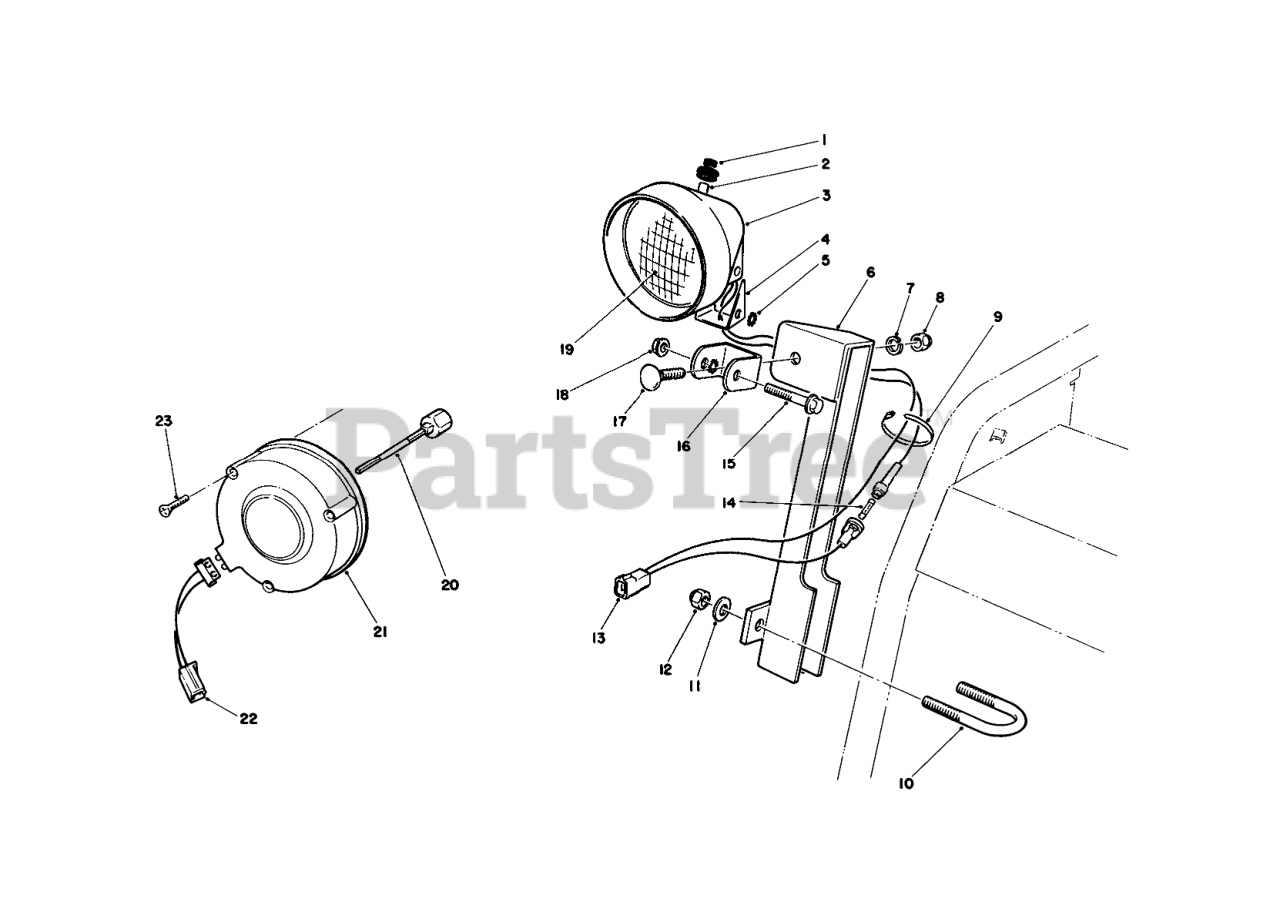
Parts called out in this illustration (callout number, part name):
2	SWITCH ASM
3	Bucket-Headlamp
4	TO BE DISCONTINED-NOT NEEDED ON PRODUCT
5	WASHER-LOCK
6	Mount-Lamp
7	WASHER-LOCK
8	NUT-HEX
9	TIE-CABLE
10	U-BOLT
11	WASHER-PLAIN
12	NUT-LOCK, NI
13	WIRE ASM
14	Fuse-7-1/2 Amp.
15	SCREW-HH
16	BRACKET
17	BOLT-CARR
18	NUT-HF
19	BEAM-SEALED
20	Shaft-Alternator, 3 Inch
21	Alternator
22	Connector-Wire
23	SELF TAP SCREW
